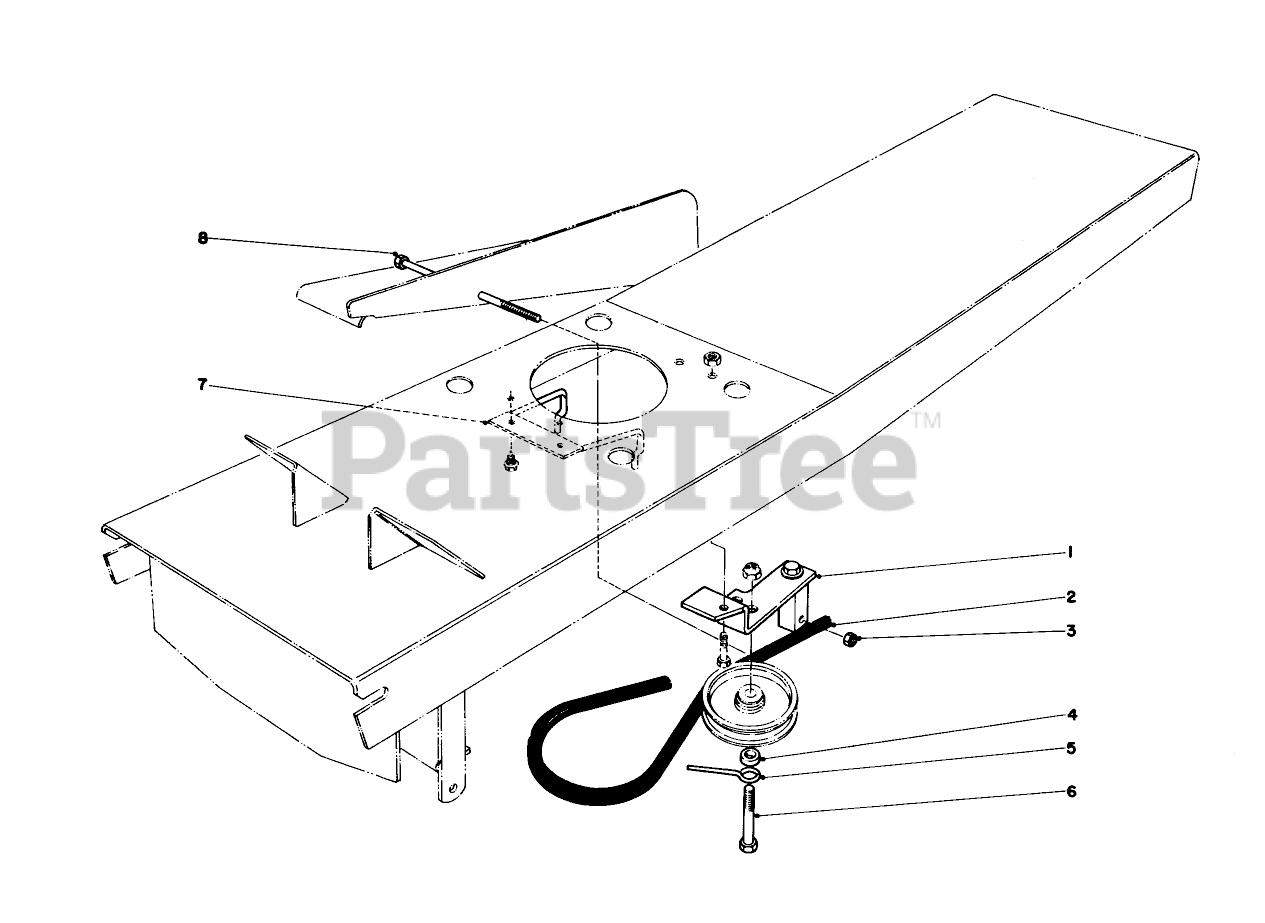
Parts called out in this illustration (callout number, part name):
1	Idler Plate Assembly
2	Belt, Special
3	NUT-LOCK, SIDE
4	COBALANCE LINK BSHG
5	Belt Retainer
6	SCREW-HH
7	Belt Guide
8	SCREW-HH
